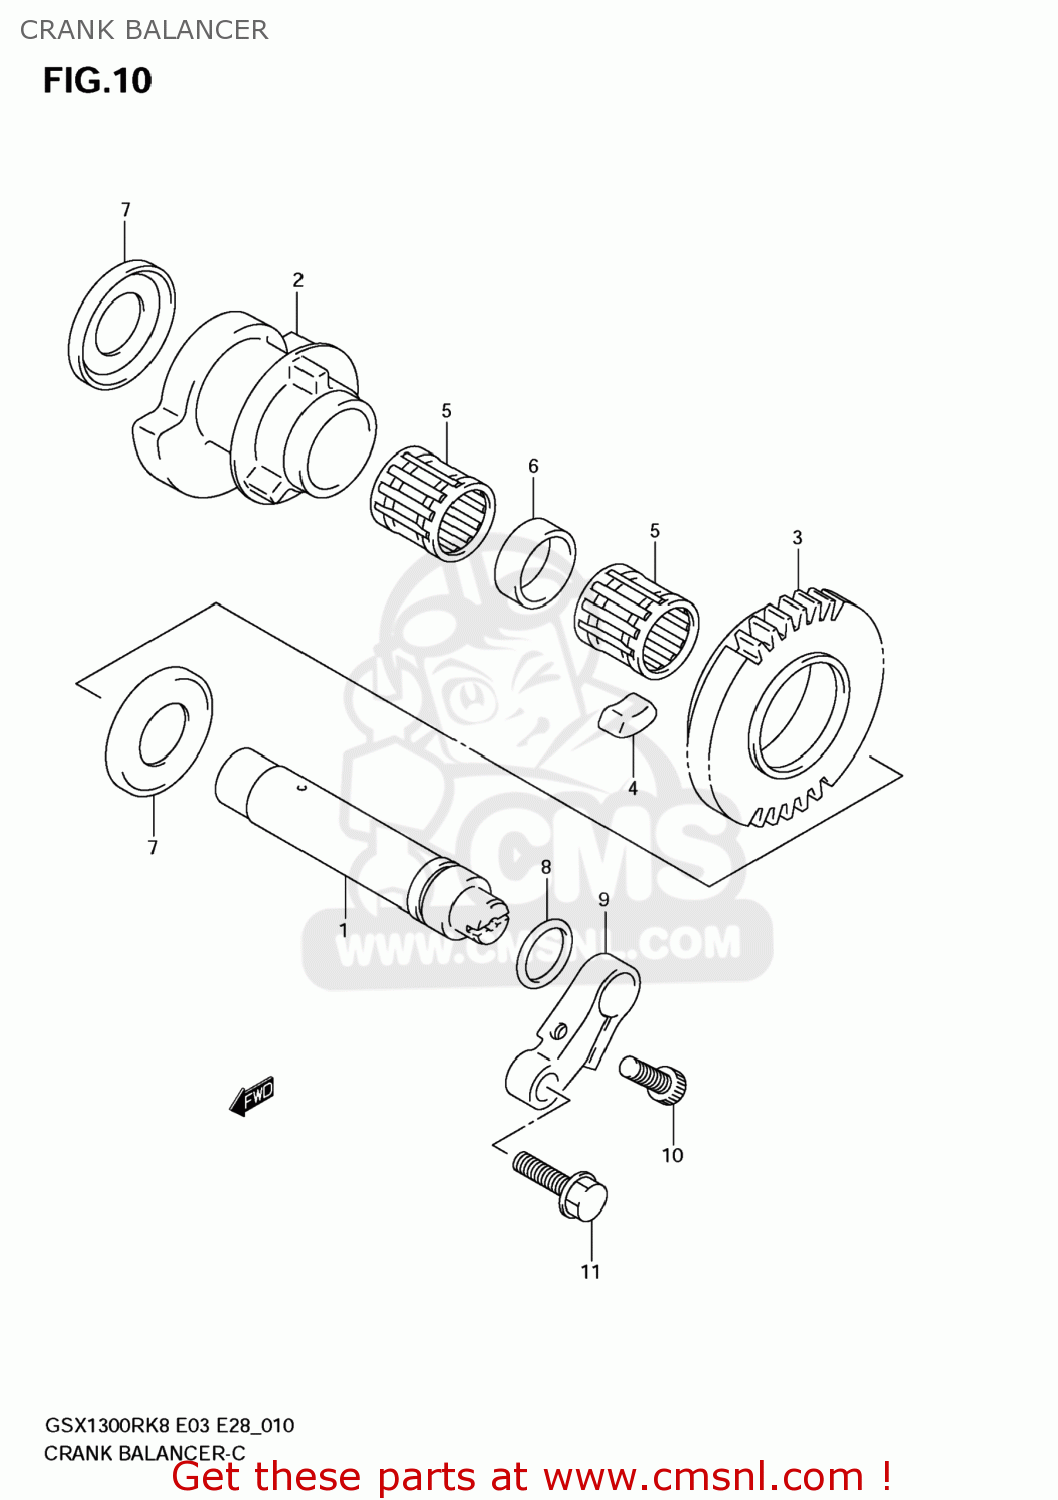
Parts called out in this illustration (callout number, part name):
1	SHAFT,CRANK BALANCER
2	BALANCER,CRANK
3	GEAR,CRANK BALANCER
4	DAMPER,BALANCER GEAR
5	BEARING(19X26X25.2)
6	SPACER(19X26X8.6)
7	WASHER
8	O RING(D:1.9,ID:16.8)
9	ARM,BALANCER SHAFT
10	BOLT
11	BOLT(6X20)
